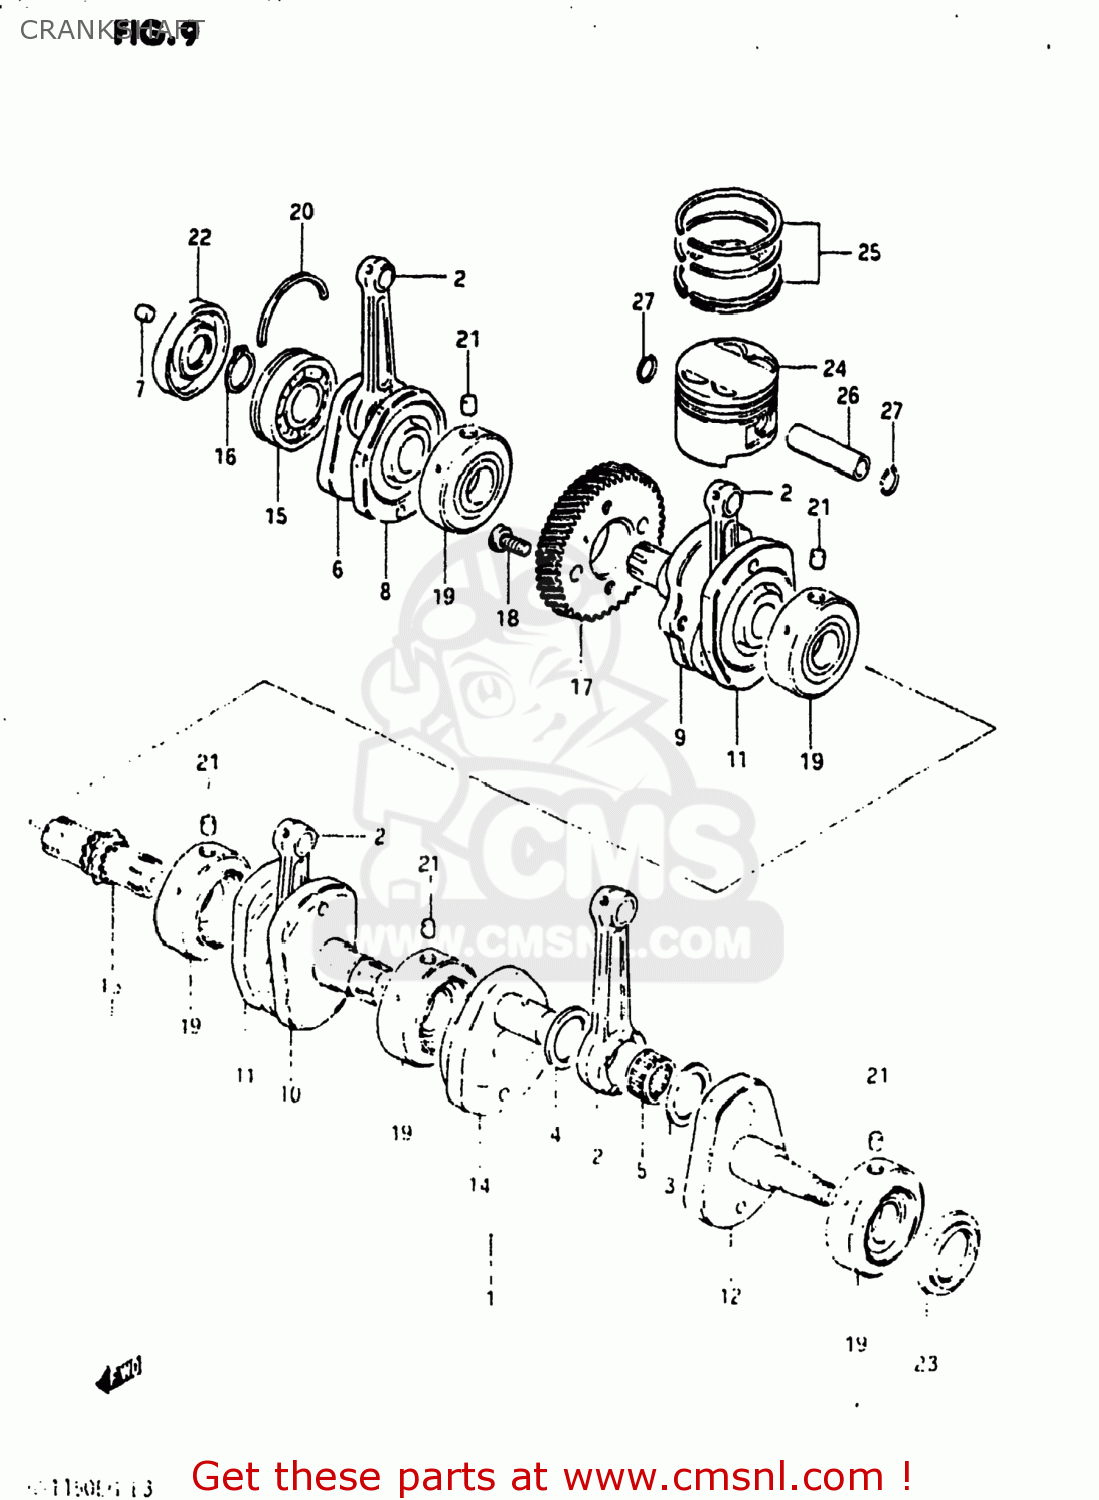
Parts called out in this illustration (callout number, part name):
1	CRANKSHAFT ASSEMBLY
2	ROD,CONNECTING
3	WASHER(31X48.5X1)
4	WASHER(31X48.5X2)
5	BEARING(31X39X21)
6	CRANKSHAFT,RIGHT
7	PIN
8	WEB,CRANK
9	CRANKSHAFT
10	CRANKSHAFT,MIDDLE,LEFT
11	WEB,CRANK,MIDDLE
12	CRANKSHAFT,LH
13	SHAFT,TIMING CHAIN DRIVE
14	WEB,CRANK,LEFT
15	BEARING(30X72X19)
16	CIRCLIP,30MM
17	GEAR,PRIMARY DRIVE
18	BOLT
19	BEARING(32X72X21)
20	C RING
21	PIN
22	SEAL,OIL(30X72X11)
23	SEAL,OIL(47.3X60X6.5)
24	PISTON (OS:0.5)
25	RING SET,PISTON
26	PIN,PISTON
27	CIRCLIP,PISTON PIN
